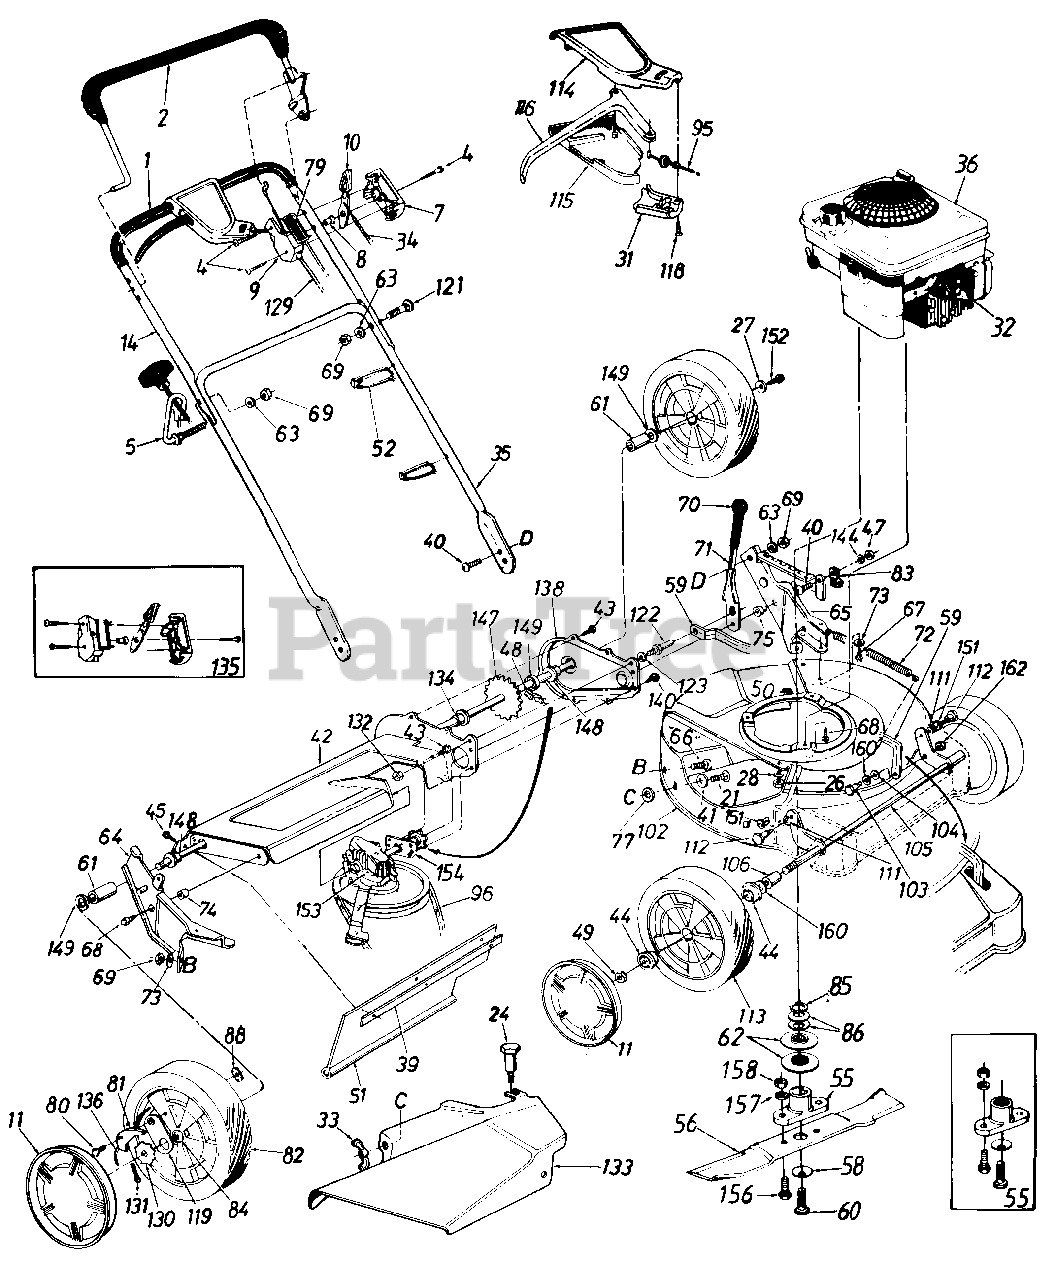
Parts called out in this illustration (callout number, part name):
1	Foam Grip
2	Control Handle Ass'y.-L.H.
4	Truss Mach. Scr. #12 x 1.5"
5	Rope Guide Bolt
7	Control Panel Half
8	Control Disc Pin
9	Clutch Panel Half
10	Throttle Control Lever
11	Hub Cap
14	Upper Handle-Painted
21	Carriage Bolt 1/4-20 x .62"*
24	Shoulder Bolt .312 Dia. x .18 Lg.-Special
26	Hex Nut 1/4-20 Thd.
27	Bell-Wash. 1/4" I.D.
28	L-Wash. 1/4" I.D.*
31	S.P. Control Cover
32	Spark Plug Insulator
33	Wing Nut w/Washer
34	Throttle Control Wire 61"
35	Lower Handle-Painted
36	Engine
39	Retaining Strip
40	Truss Mach. Scr. 5/16-18 x .75"
41	Fl-Wash. .344" I.D. x .62"
44	Flange Ball Bearing 1/2" I.D.
45	Hex AB-Tap Scr. 1/4 x .62"
47	Hex Patch L-Nut 3/8-24 Thd.
48	#48 Chain .5" Pitch x 30 Links
49	Hex L-Nut 1/2-20 Thd.
52	Cable Tie
55	Blade Adapter Kit
56	21" Blade
58	Bell-Wash. .46" I.D. x 1.13"
59	Height Adj. Connecting Arm
60	Hex Bolt 7/16-20 x 1.5" Lg. (Grade 5)
61	Spacer .513" I.D. x .703" O.D. x .69" Lg.
62	Serrated Pulley Half
63	L-Wash. 5/16" I.D.*
64	R.H. Handle Wheel Brkt. Ass'y.
65	L.H. Handle Wheel Brkt. Ass'y.
66	Carriage Bolt 5/16-18 x .62"*
67	Hex B-Tap Scr. 5/16-18
68	Hex TT-Tap Scr. 3/8-16
69	Hex Nut 5/16-18 Thd.
71	Height Adj. Lever
72	Extension Spring 8" Lg.
73	Bell-Wash. 5/16" I.D.
74	Spacer
75	Shld. Spacer .500" Dia.
77	Bolt Retainer 1/4 x .50" O.D.
79	Control Label
80	Shld. Scr. 342" Dia. x .268
81	Pawl
82	Wheel Ass'y. Comp.
84	Bearing 1/2" I.D.
85	Bell Washer 1.01" I.D.
86	Crankshaft Spacer
88	Flat Weld Nut 1/4-20 Thd.
95	S.P. Cable 48" Lg.
96	"V"-Belt
102	21" DeckAss'y.
103	Shld. Bolt 5" Dia. x .295
104	Bell-Wash. .515" I.D. x 1.0"
105	Front Axle Ass'y.
106	Sleeve .526" l.D. x .690" O.D. x .880" Lg.
111	Intern. L-Wash. 3/8 I.D.*
112	Shld. Bolt .575" Dia. x .42
113	Wheel Ass'y. Comp.
114	Self-Propelled Control Cover
115	Self-Propelled Control Cover
116	Control Lever
118	Fl-"C"-Sunk Hd. Tap Scr. #10 x .75" Lg.
119	Pawl Plate
121	Curved Carr. Bolt 5/16-18 x 1.38" Lg.
122	Shld. Pin 3/8-24 x 1.43" Lg.
123	L-Wash. 3/8" l.D.*
129	Control Cable 43" Lg.
130	Ratchet Wheel 1.62" O.D.
131	Cotter Pin 1/8" Dia. x 1.00" Lg.
132	Hex Jam Nut 3/8-24 Thd.
133	Side Chute Deflector Ass'y.
134	Hex Flange Bearing
135	Kit-Control Housing Comp.
136	Spring-Nylon
144	Fl-Wash. .385" I.D. x .87"
147	Rear Shaft Ass'y. 21.94" Lg.
148	Hex Flange Bearing .506" I.D. Plastic
149	Fl-Wash. .531" I.D. x .930"
151	Flanged Nyliner Brg.
152	Hex Bolt 1/4-20 x .62" Lg. (Grade S)
153	Transmission Comp.
156	Hex Bolt 3/8-24 x 1.0" Lg.
157	L-Wash. 3/8" I.D.*
158	Hex Nut 3/8-24 Thd.
160	Fl-Wash. .51" I.D. x .75" O.D.
162	Hex Jam Nut 3/8-16 Thd.
